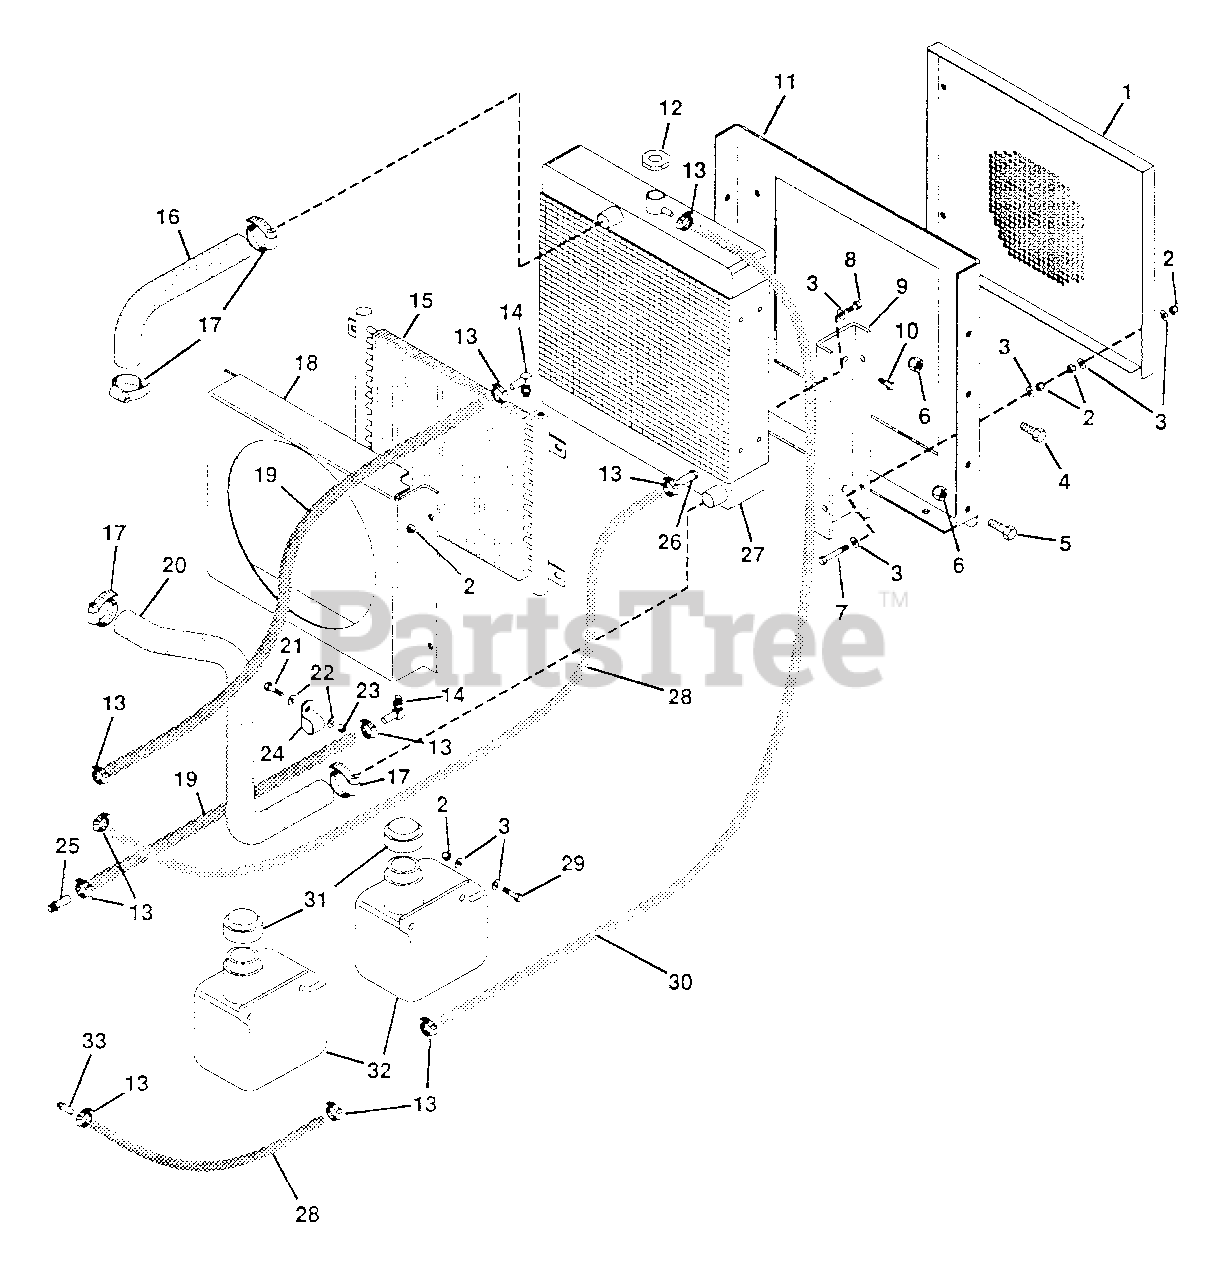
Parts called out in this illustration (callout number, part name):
1	Cover, Air
2	Nut, Lock 5/16-18
3	Washer, Flat .344x.688x.065
4	Bolt, Hex 1/2-13x1.00
5	Bolt, Hex 1/2-13x1.50
6	Nut, Lock 1/2-13
7	Bolt, Hex 5/16-18x1.75
8	Bolt, Hex 5/16-18x.75
9	Bracket, Radiator
10	Bolt, Hex 5/16-18x.50
11	Mount, Radiator
12	Cap, Radiator
13	Clamp, Hose
14	Adapter, #4601-6-6
15	Cooler, Air
16	Hose, Upper Radiator
17	Clamp, Hose
18	Cover, Fan
19	Hydraulic Hose,
20	Hose, Lower Radiator
21	Bolt, Hex 3/8-16x1.00
22	Washer, Flat .406x.812x.065
23	Nut, Lock 3/8-16
24	Clamp, Nylon
25	Adapter, #4604-6-6
26	Adapter
27	Radiator, Flat Plate
28	Fuel Line .5 OD x .25 ID,
29	Bolt, Hex 5/16-18x1.00
30	Hose 5/16 ID,
31	Cap, 1-5/8 Vented
32	Tank, Plastic 1.5 Qt.
33	Connector, Hose
